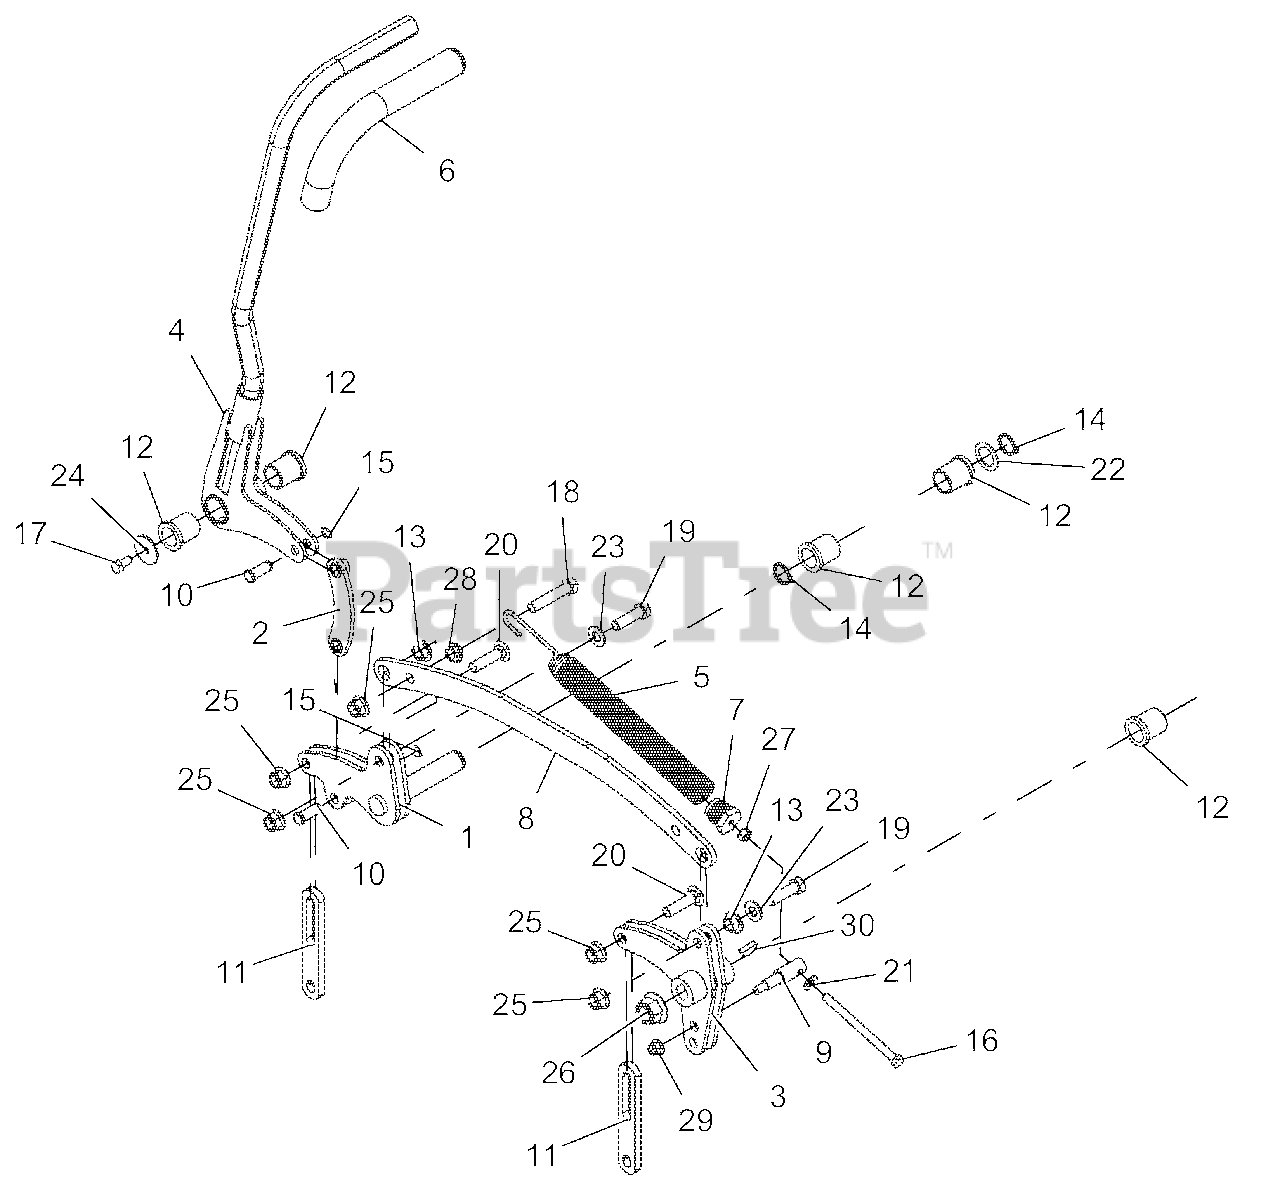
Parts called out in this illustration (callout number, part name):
1	WLDMT, DECK LIFT PROSTANCE
2	WLDMT, DECK LIFT LINK
3	WLDMT, TAPERED HUB PROSTANCE (BLACK)
4	WLDMT, HANDLE PROPANE LIFT
5	SPRG, DECK LIFT
6	GRIP, HANDLEBAR
7	PLUG, SPRG
8	ARM, DECK LIFT
9	TRUNION, DECK LIFT
10	PIN, CLEVIS .500 SNAP RING
11	LINK, DECK LIFT - LONG
12	BSHG-FLG 1.00X1.25X1.5X1.5
13	BSHG, FLANGE .515X.750X.420X1.12
14	RG-RTNG-EXT 1.00X.078
15	RG-RTNG-EXT .500x.050
16	BLT-HEX .38-16X5.00 GR5 YWZC
17	BLT-HEX .38-16X.75 GR5 YWZC
18	BLT-HEX .50-13X2.50 GR5 YWZC
19	BLT-HEX .50-13X1.75 GR5 YWZC
20	BLT-RDHDSQNK .50-13X2.00 G5 Y
21	WSHR-FL-STL.406X.812X.065 YWZ
22	WSHR-FL-STL 1.010X1.505X.062 YWZC
23	WSHR-FL-STL.531X1.06X.095YWZC
24	WSHR-FL-STL .380X1.50X.125 YWZC
25	NUT-LK-NYL-FLG .50-13 YWZC
26	NUT-LK-NYL-FLG .75-10 YWZC
27	NUT-HEX .38-16 YWZC
28	NUT .50-13 WIZ FLANGE
29	NUT-LK-NYL-FLG .38-16 YWZC
30	KEY, WDRF .25 X 1.00 HRD #15
